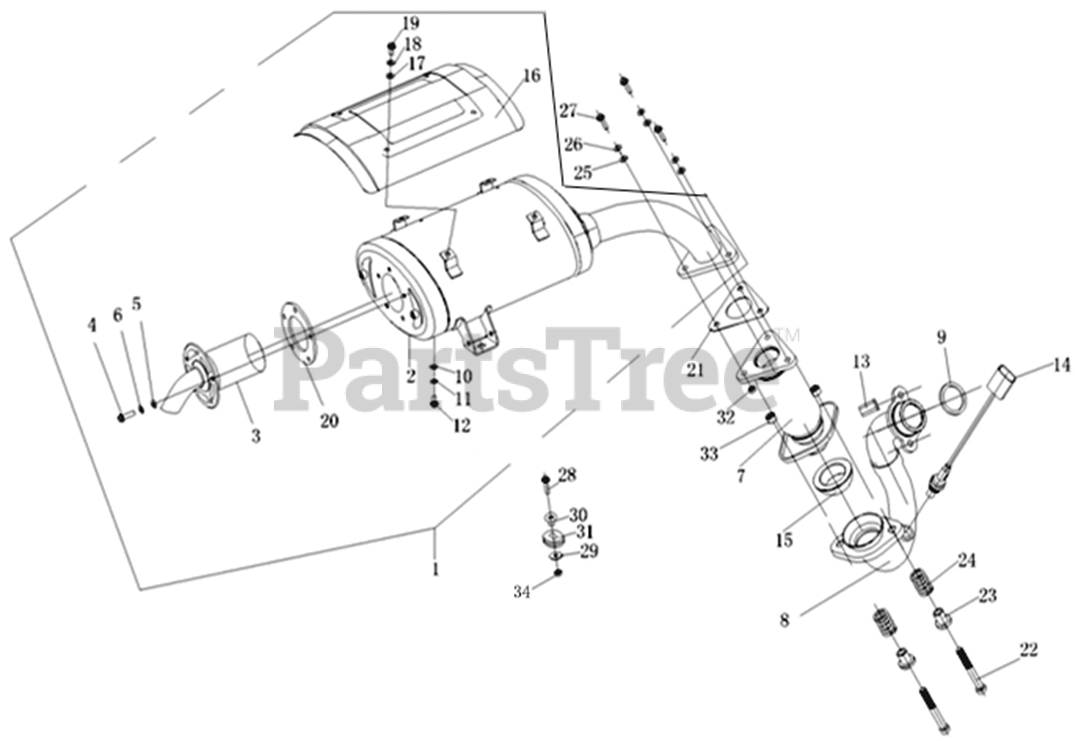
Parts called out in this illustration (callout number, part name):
1	MUFFLER ASSEMBLY
4	FLANGE HEAD BOLT M6-0.75x16
5	FLAT WASHER 6x18x1
6	WASHER - SPRING LOCK 8
7	FLEX EXHAUST PIPE I
8	EXHAUST PIPE
9	EXHAUST GASKET
11	SPRING WASHER
12	HEXAGON BOLT M10X1.25X16
13	CAP NUT M8x22
14	OXYGEN SENSOR ASSEMBLY-EFI
15	EXHAUST GASKET
16	MUFFLER HEAT SHIELD
17	WASHER - SPRING LOCK 8
18	FLAT WASHER 6x18x1
19	BOLT HEX SOCKET M6X16
20	TAILPIPE GASKET
21	EXHAUST PIPE GASKET
22	HEX HEAD FLANGE BOLT M10X1.25X80
23	EXHAUST SPACER
24	EXHAUST VALVE SPRING
26	SPRING WASHER-8
27	HEXAGON FLANGE BOLT M8X30
28	HEX FLANGE BOLT M6X25
29	FLAT WASHER 6X25X2
31	RUBBER WASHER
32	HEXAGON FLANGE NUT M8
33	NUT M10X1.25
34	HEXAGON FLANGE LOCKED NUT M6
